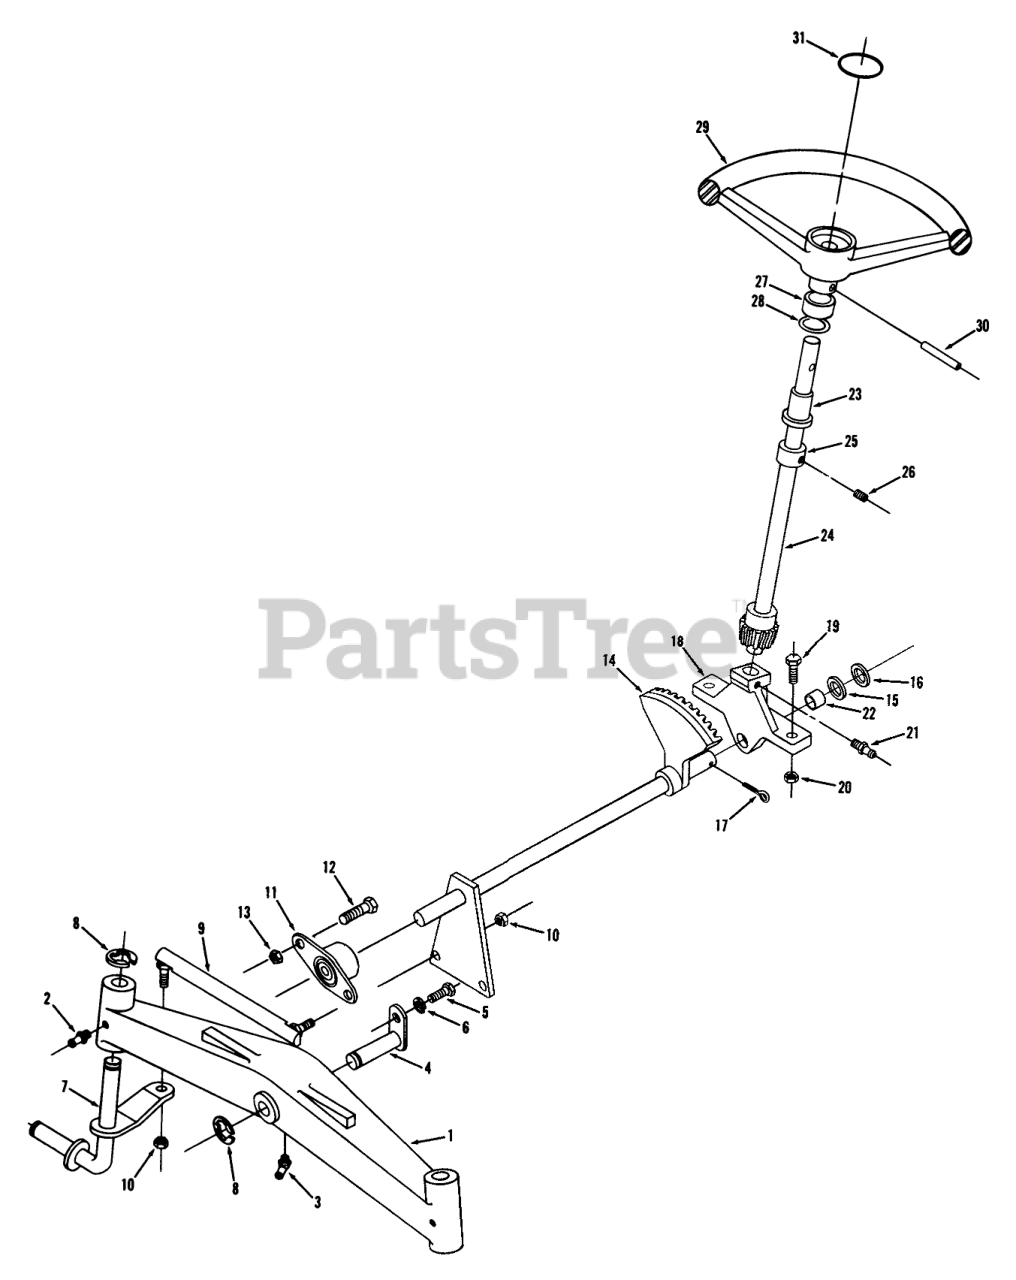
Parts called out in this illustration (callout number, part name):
1	AXLE-FRONT
2	Zerk
3	FITTING-GREASE
4	PIN AND PLATE ASM
5	H H C S
6	Lockwasher
7	Front Spindle LH
7	Front Spindle RH
8	E-RING
9	Tie Rod RH
9	Tie Rod LH
10	NUT-6
11	BEARING-FLANGED
12	BOLT
13	Nut
14	Assy-Steering
15	WASHER-SHIM
16	WASHER
17	PIN-4
18	Support
19	Bolt
20	Nut
21	Zerk
22	BEARING-BRONZE
23	BEARING
24	Upper Steering Shaft
25	Collar
26	SCREW-SET
27	Collar
28	WASHER-BOWED
29	STEERING WH 13" SOFT
30	Pin-Roll
31	STEERING WHEEL INSE
